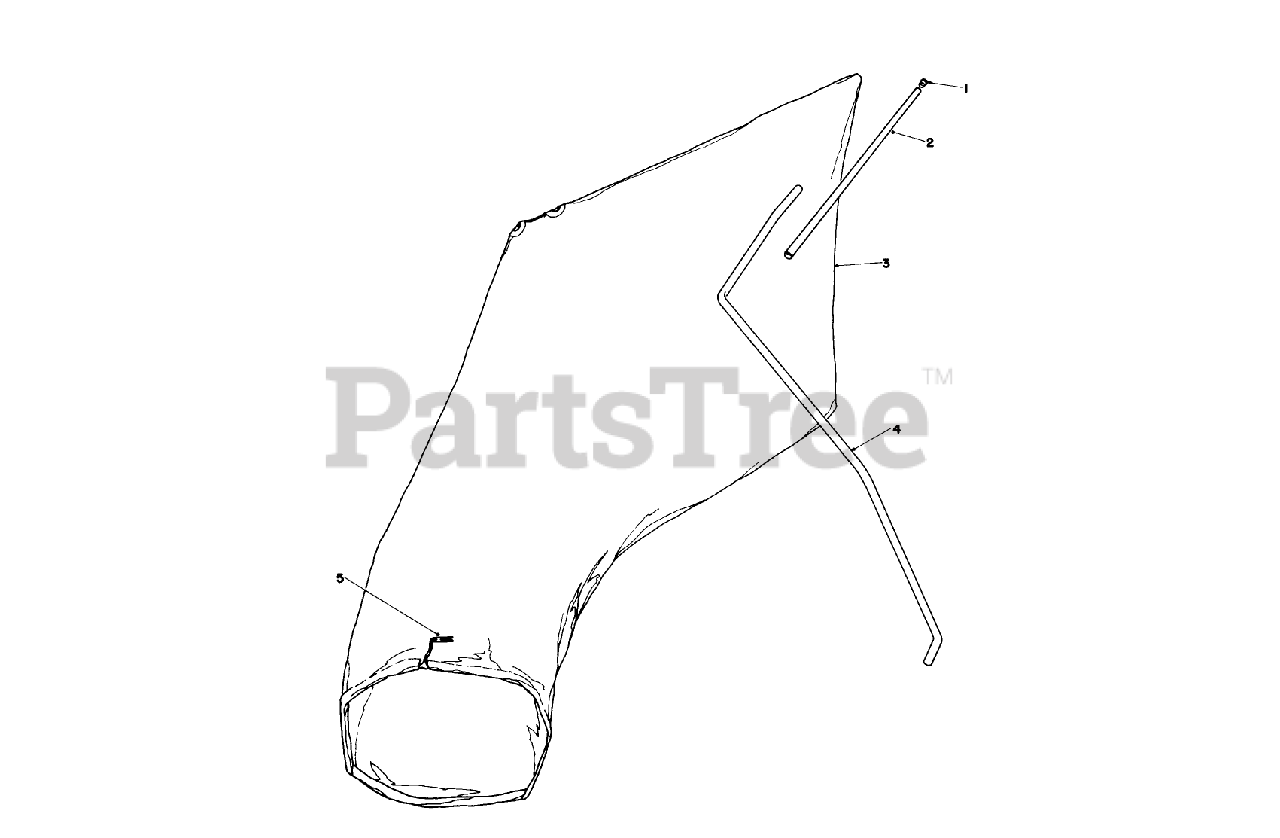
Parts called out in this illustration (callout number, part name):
2	BAG HANGER TUBE
4	HANGER ROD
5	BAG CORD FASTENER
